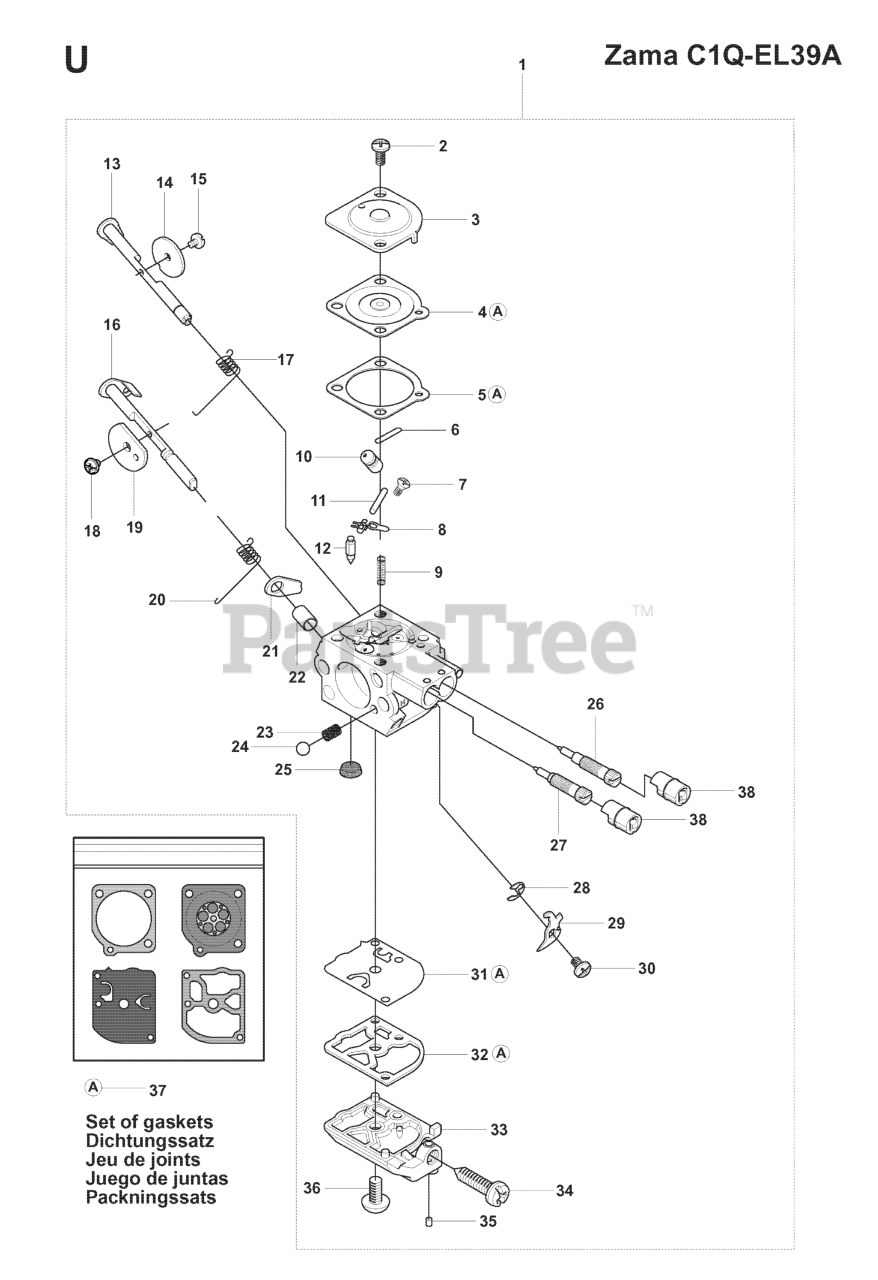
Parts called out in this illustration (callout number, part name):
1	CARBURETTOR C1Q-EL39A
9	SPRING
11	PIN RETAINING SCREW
12	INLET NEEDLE
13	SHAFT ASSY
16	SHAFT ASSY
17	RETURN SPRING
25	FUEL INLET SCREEN
26	SCREW IDLE MIXTURE
27	SCREW MAIN MIXTURE
31	PUMP DIAPHRAGM
37	GASKET KIT (ZAMA GND39)
38	LIMITER CAP KIT
